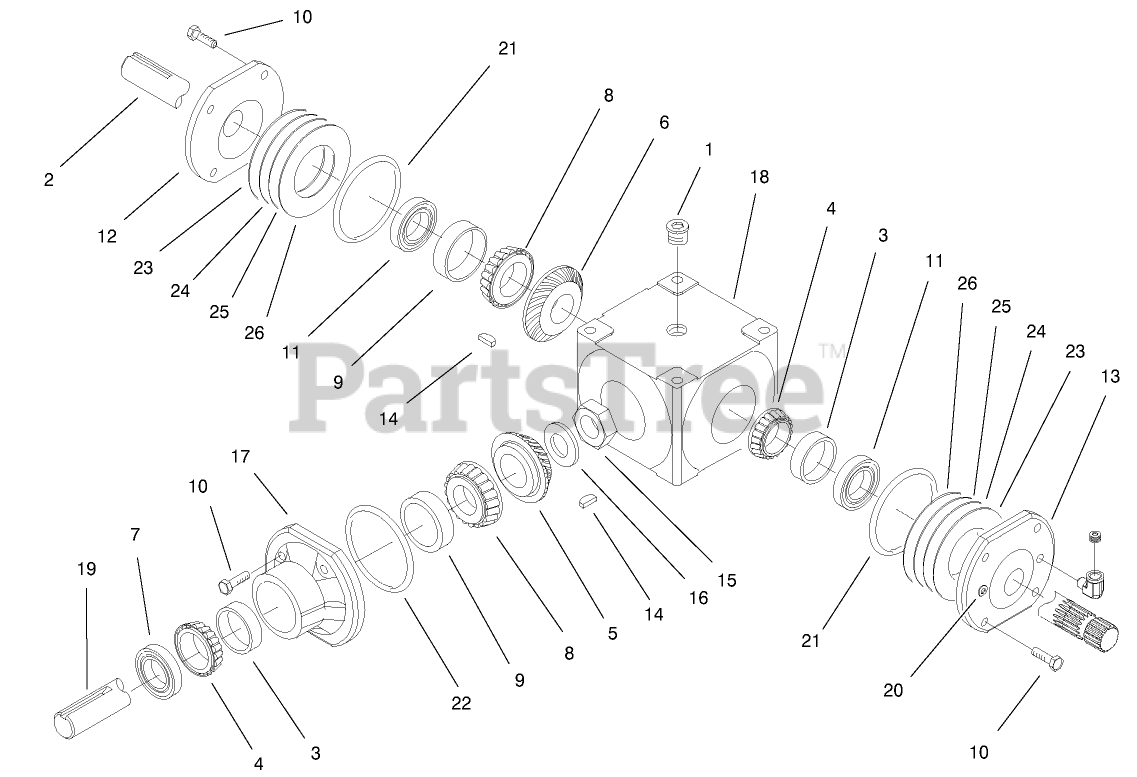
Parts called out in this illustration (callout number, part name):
2	SHAFT-CROSS
3	Bearing-Cup
4	Bearing-Cone
5	GEAR-SPIRAL, RH
6	GEAR-SPIRAL, LH
8	BEARING-CONE
9	BEARING-CUP
10	SCREW-HH
11	SEAL
12	CAP-END
13	END CAP W/ DRAIN PLUGS
14	OBS KEY
15	NUT-LOCK
16	WASHER
17	HOUSING-PINION
19	SHAFT-PINION
21	O-RING
22	O-RING
23	SHIM-GREEN (.003)
24	SHIM-BLUE (.005)
25	SHIM - BROWN (.010)
26	SHIM-YELLOW (.020IN)
